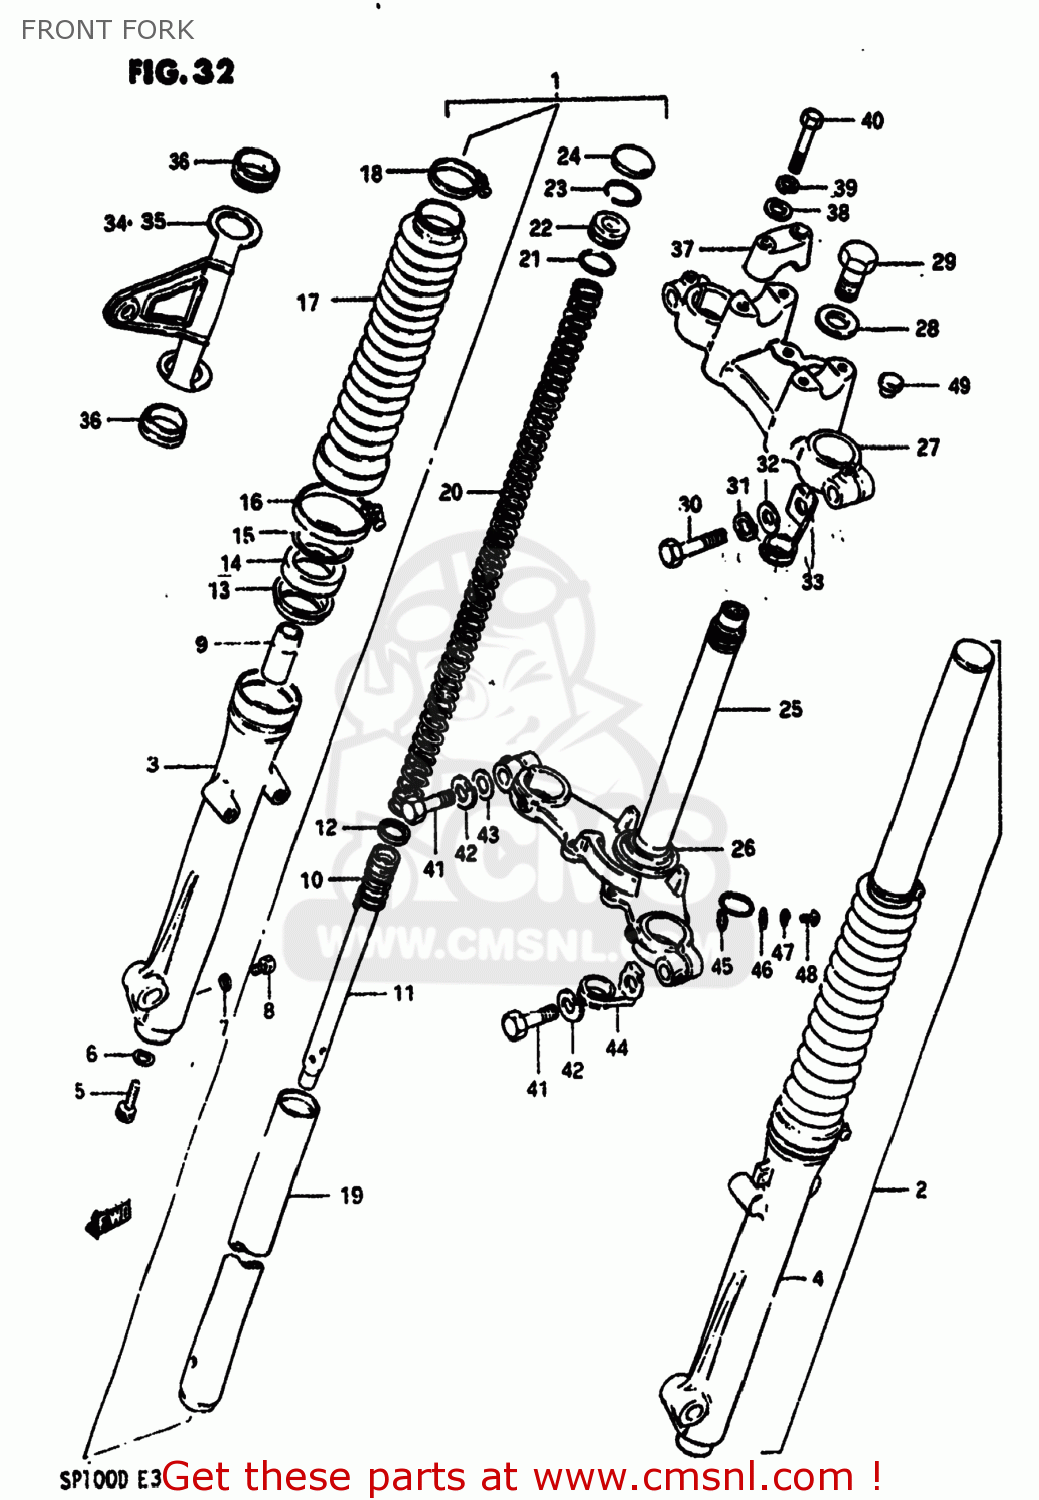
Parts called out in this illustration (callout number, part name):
1	DAMPER ASSEMBLY,RIGHT
2	DAMPER ASSEMBLY,LEFT
3	TUBE,FORK,OUTER,RIGHT
4	TUBE,OUTER,LEFT
5	BOLT(8X27)
6	GASKET (NAS)
7	GASKET,DRAIN,PLUG (NAS)
8	BOLT
9	PIECE,OIL LOCK
10	SPRING,REBOUND
11	CYLINDER,FRONT FORK
12	RING,FRONT FORK PISTON
13	SPACER,SEAL
14	OIL SEAL,FRONT FORK
15	SEAL,OIL STOPPER RING
16	CLAMP
17	BOOT
18	BAND
19	TUBE,FORK,INNER
20	SPRING,FRONT FORK
21	O RING
22	SEAT,SPRING
23	RING,STOPPER
24	CAP,FRONT FORK
25	STEM,STEERING
26	RACE,STEERING OUTER LWR
27	HEAD,STEERING STEM
28	WASHER,STEM HEAD(10.5X30X3.2)
29	BOLT,FORK INNER TUBE
30	BOLT
31	LOCK WASHER
32	WASHER
33	GUIDE,CABLE
34	BRACKET,HEADLAMP,RIGHT
35	BRACKET,HEADLAMP,LEFT
36	CUSHION,HEADLAMP BRACKET
37	HOLDER,HANDLEBAR
38	WASHER
39	LOCK WASHER
40	BOLT
41	BOLT,M10X1.25X
42	LOCK WASHER
43	WASHER
44	GUIDE,CABLE
45	CLIP
46	WASHER
47	LOCK WASHER
48	SCREW 6X12
49	PLUG(OD:12)
